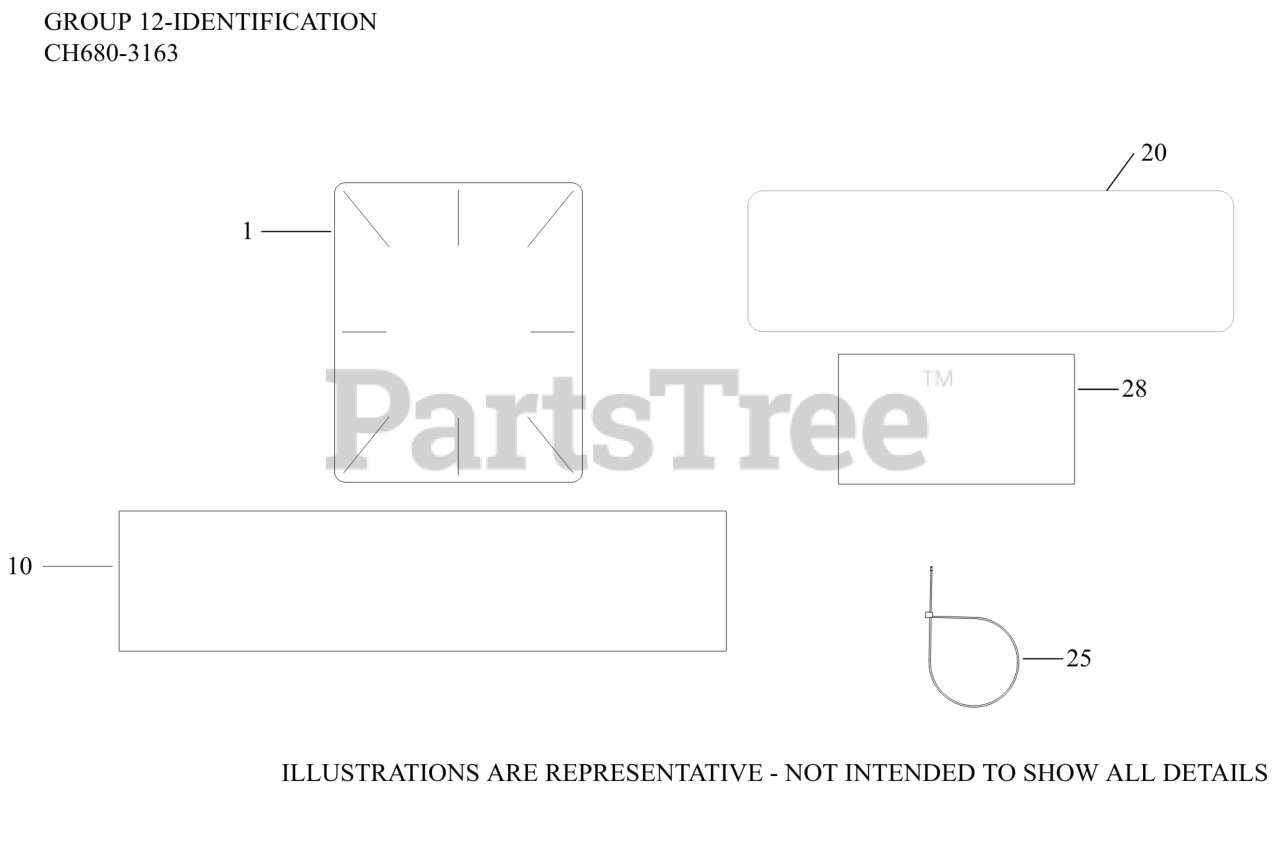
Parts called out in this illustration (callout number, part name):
1	LABEL, CLEAR LAMINATION
10	DECAL, STOPPING INSTRUCTION
20	DECAL LPAC, 22.5 HP/674cc/CH680
28	DECAL, USA
